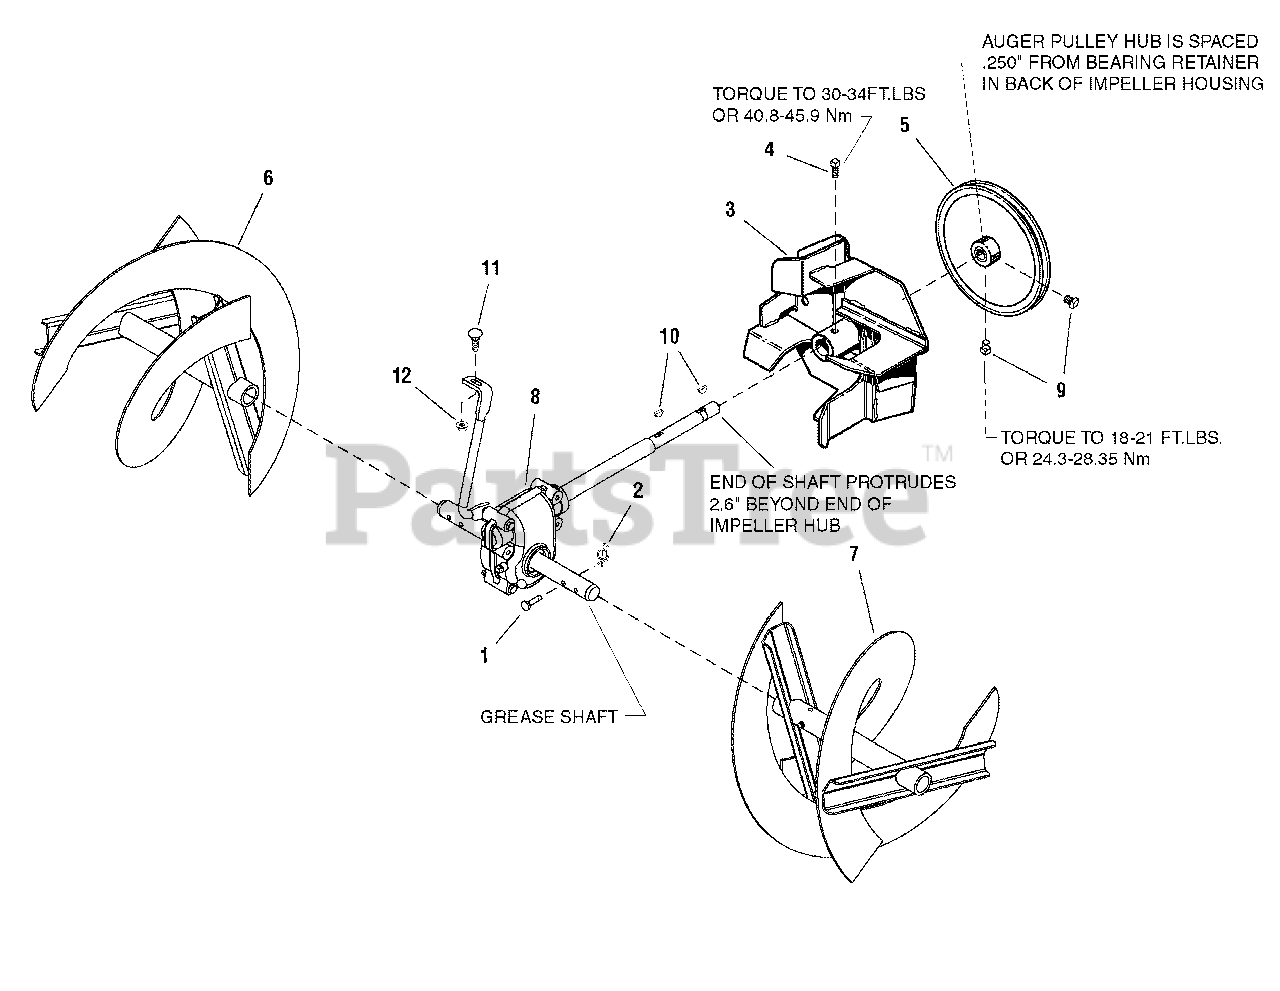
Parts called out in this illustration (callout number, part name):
1	PIN, SHEAR
2	COTTER PIN, 1/4" Self Locking
3	IMPELLER ASSEMBLY, Large Frame Snow
4	SCREW, Set, Square Head Cup Point 3/8-16 x 1/2 G8
5	PULLEY, w/Hub
6	AUGER ASSEMBLY, 38" R.H.
7	AUGER ASSEMBLY, 38" L.H.
8	GEAR BOX ASSEMBLY
9	SCREW, Set, Square Head Cup Point 5/16-18 x 1/2 G8
10	KEY, Woodruff
11	CARRIAGE BOLT, 5/16-18 x 3/4 G5
12	NUT, Hex Flange Whiz Lock, 5/16-18
